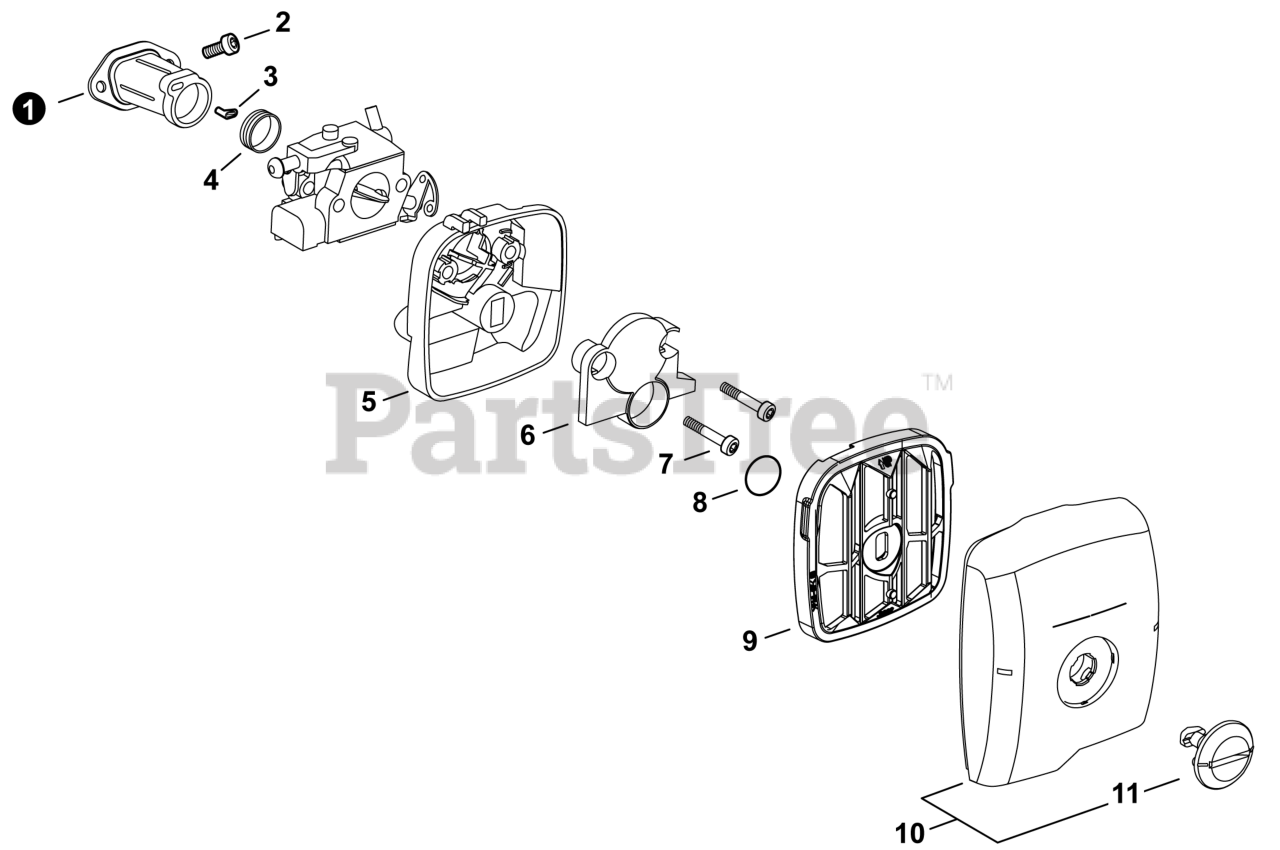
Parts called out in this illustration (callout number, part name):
1	BELLOWS, INTAKE
2	BOLT, TORX 5x12
3	COLLAR 3.2x6.5
4	SPRING, TENSION
5	CASE, AIR FILTER
6	PLATE, PREVENT
7	BOLT, TORX 5x50
9	FILTER, AIR - MESH
10	COVER ASSY, AIR FILTER
11	KNOB, AIR FILTER COVER
